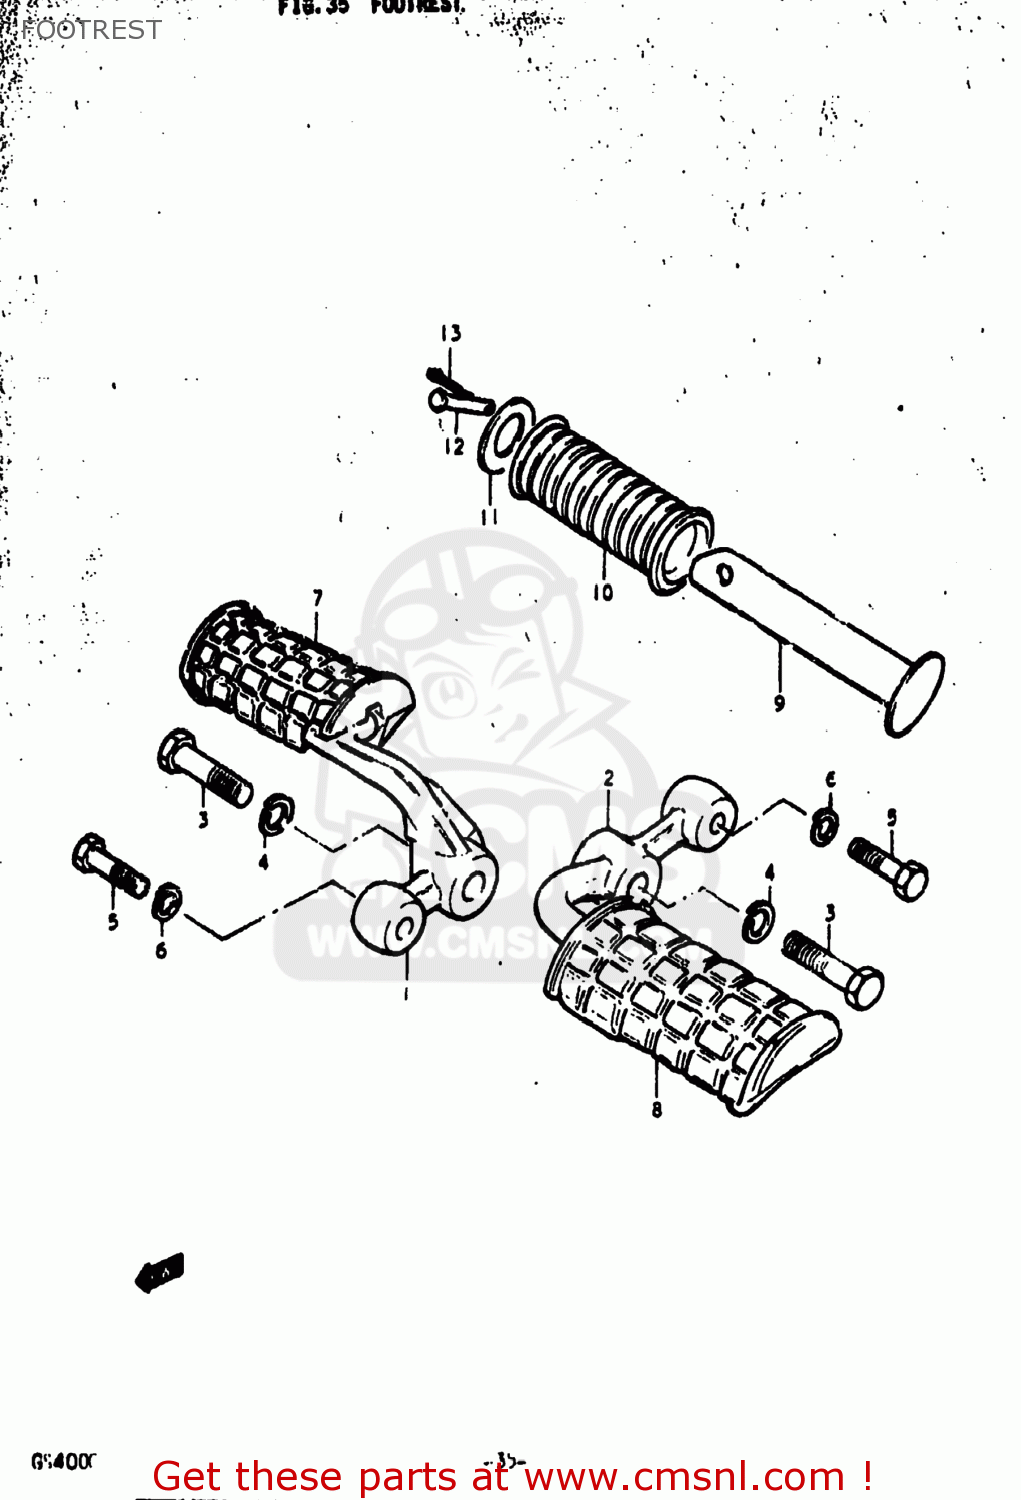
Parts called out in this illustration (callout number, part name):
1	BAR,FRONT FOOTREST
2	BAR,FRONT FOOTREST,LEFT
3	BOLT
4	LOCK WASHER
5	BOLT 8X40
6	LOCK WASHER
7	RUBBER,FR FOOTREST,R
8	RUBBER,FOOTREST
9	BAR,FOOTREST RUBBER
10	RUBBER,PILLION FOOTREST
11	WASHER (19.5X32X2)
12	PIN
13	PIN 20X20
